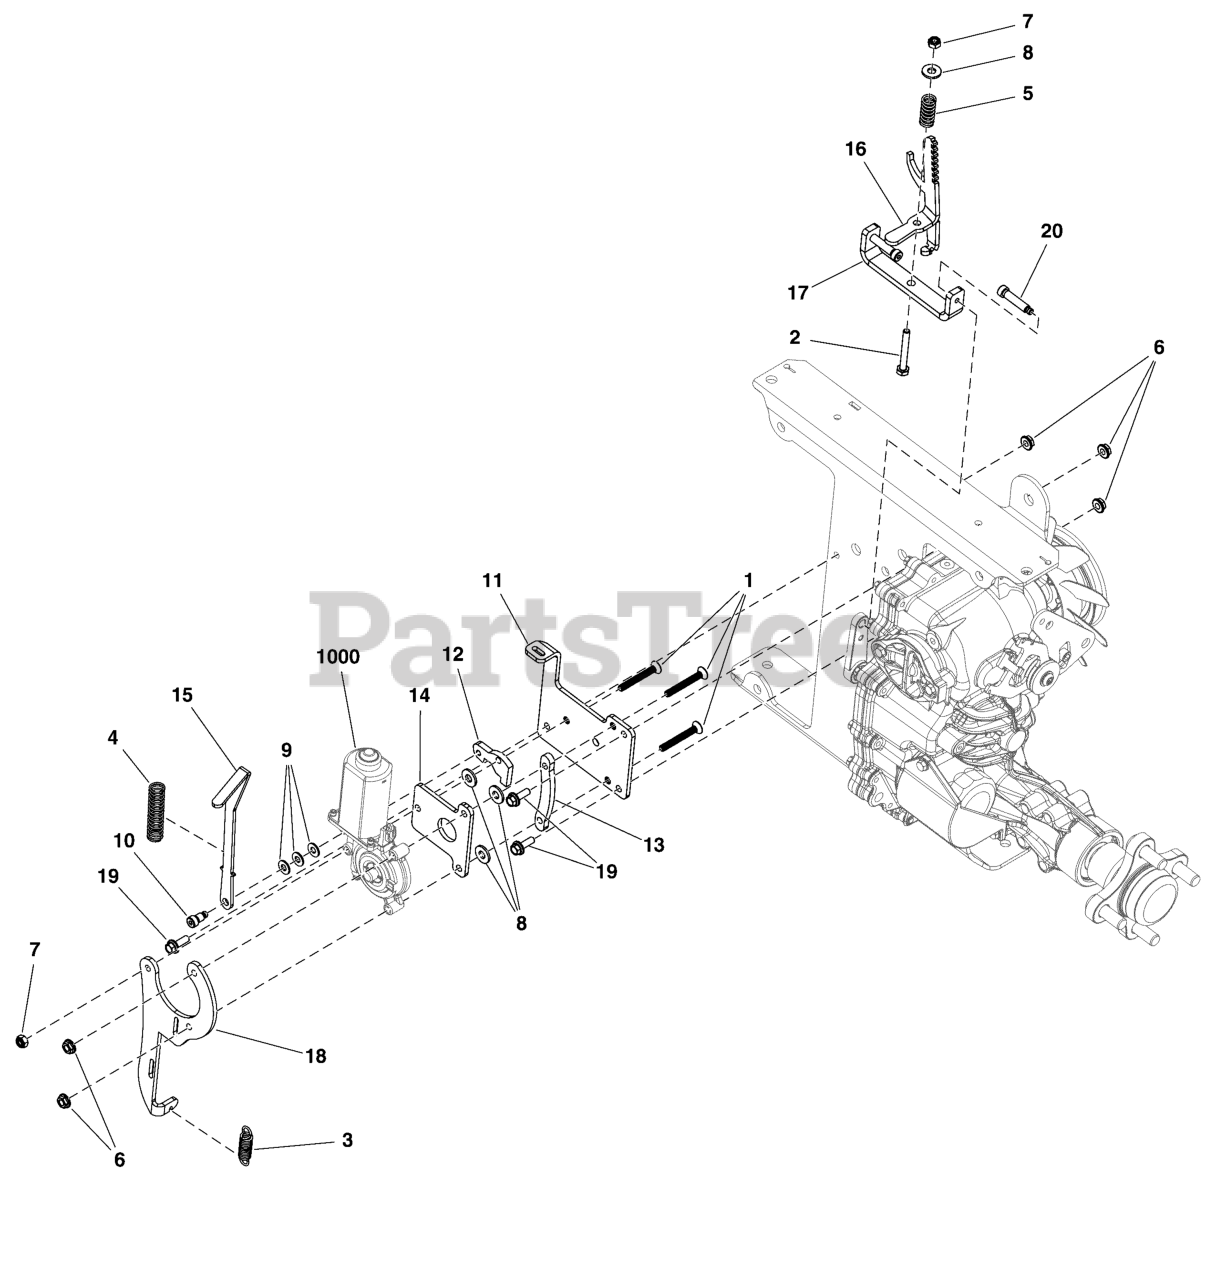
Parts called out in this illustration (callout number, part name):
1	SCREW, 1/4-20 X 2, PHLPS, SS
2	BOLT, 1/4-20 X 2", GD5
3	SPRING, EXTENSION, #29
4	SPRING, COMPRESSION, #29
5	SPRING, COMPRESSION, #21
6	NUT, 1/4-20 HEX SERR. FLANGE
7	NUT, 1/4-20 HEX NYLON LOCK
8	WASHER, 1/4 SAE, CZ
9	WASHER, 1/4 SAE
10	BOLT, 5/16 X 1/2, SHLDR, SS
11	PLATE, BRAKE BACKING
12	PLATE, BRAKE CAM, CZ
13	PLATE, BRAKE SPACER - BLK
14	PLATE, CAM COVER, CZ
15	PLATE, BRAKE RELEASE LEVER,CZ
16	WELD, BRAKE GEAR RACK,CZ
17	ARM, Lever
18	PLATE, SWITCH MOUNT, CZ
19	BOLT, 1/4-20 X 3/4, FLANGE, CZ
20	BOLT, 5/16 X 1-1/4, SHLDR, SS
1000	Refer to: Electrical Group
